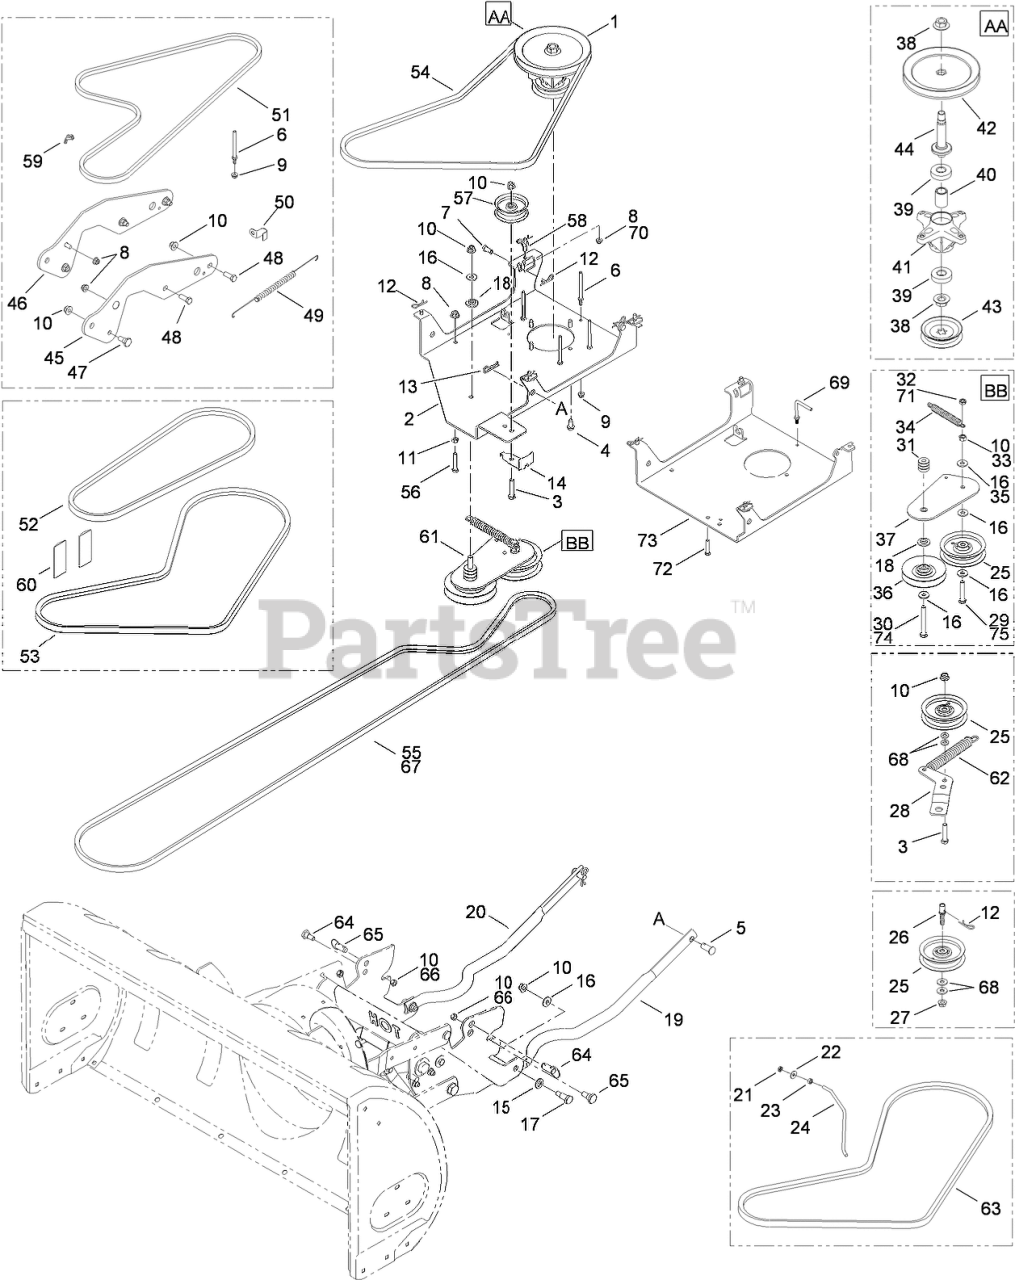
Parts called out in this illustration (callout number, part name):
1	7 INCH PULLEY SPINDLE ASM
2	BRACKET-MOUNTING, PULLEY
3	SCREW-HH
4	SCREW-HWH
5	PIN-CLEVIS
6	KEEPER-BELT
7	PIN-CLEVIS
8	NUT-LOCK, FLANGE
9	NUT-LOCK, FLANGE
10	NUT-LOCK, FLANGE
11	NUT-HEX
12	PIN-CLICK
13	PIN-CLIP, INTERNAL
14	KEEPER-BELT
15	WASHER-FLAT
16	WASHER-ISOMOUNT
17	BOLT-SHOULDER
18	SPACER-SHOULDER
19	TUBE-SUPPORT, LH
20	TUBE-SUPPORT, RH
21	NUT-HEX, JAM
22	WASHER-SPRING
23	NUT-HEX
24	ROD-KEEPER, BELT
25	PULLEY-IDLER, 3.50 INCH
26	SPACER-IDLER
27	NUT-LOCK, FLANGE
28	BRACKET-IDLER
29	SCREW-HH
30	SCREW-HH
31	SPACER
32	NUT-NYLON, JAM
33	NUT-HEX
34	SPRING-EXTENSION
35	WASHER-LOCK
36	PULLEY
37	IDLER PIVOT ASM
38	NUT-LOCK, FLANGE
39	BEARING-BALL
40	SPACER
41	HOUSING-SPINDLE, DECK
42	PULLEY-DECK, 7 INCH
43	PULLEY-3.75 INCH
44	SHAFT-SPINDLE
45	LH BRACKET ASM
46	RH BRACKET ASM
47	BOLT-SHOULDER
48	SCREW-HH
49	SPRING-EXTENSION
51	BELT- V TYPE
52	BELT-V, A SECTION
53	BELT-V TYPE
54	BELT-V
55	BELT-V TYPE
56	BOLT-HH
57	PULLEY-IDLER, FLAT
59	NUT-WING
60	REFLECTOR
61	DOUBLER IDLER BRACKET ASM
62	SPRING-EXTENSION
63	V-BELT, B SECTION
64	BOLT-SHOULDER
65	PIN-RELEASE, QUICK
66	NUT-LOCK
67	BELT-V
68	WASHER-FLAT
69	PIN-KEEPER, BELT
70	NUT-HEX, CENTER LOCK
72	SCREW-HH
73	BRACKET-MOUNTING, PULLEY
74	BOLT-HEX
75	SCREW-HH
